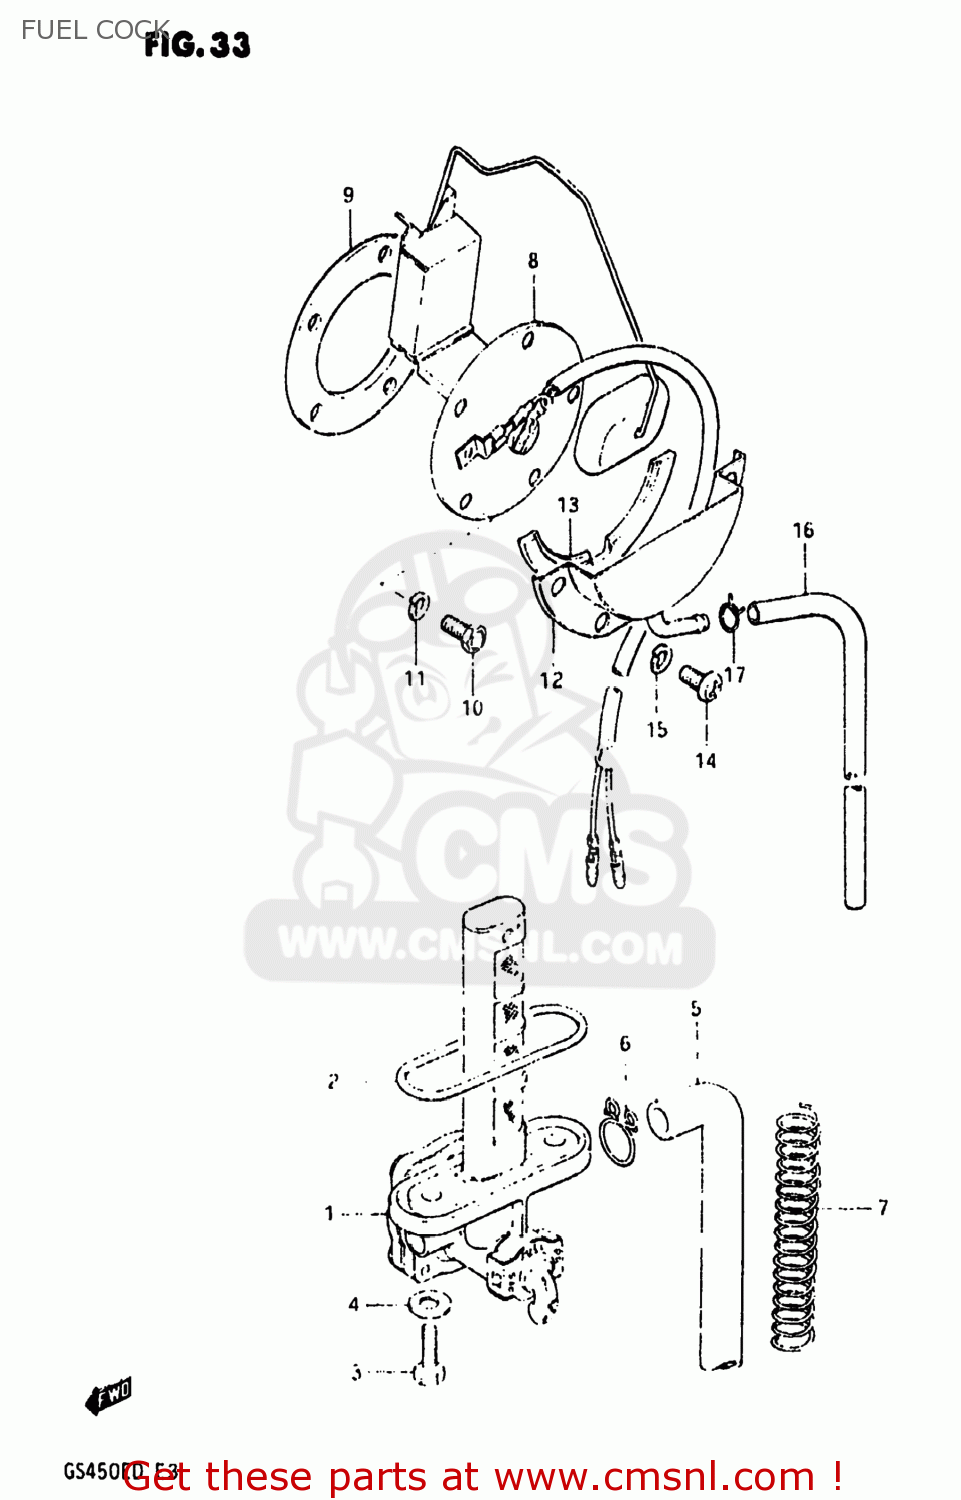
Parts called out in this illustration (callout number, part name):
1	COCK ASSEMBLY,FUEL
2	O RING
3	SCREW
4	GASKET
5	HOSE
6	CLIP
7	SPRING
8	GAUGE ASSEMBLY,FUEL LEVEL
9	GASKET,FUEL LEVEL GAUGE (NAS)
10	BOLT
11	LOCK WASHER
12	PLATE,FUEL DRAIN
13	GASKET (NAS)
14	SCREW
15	LOCK WASHER
16	HOSE,FUEL
17	CLIP
